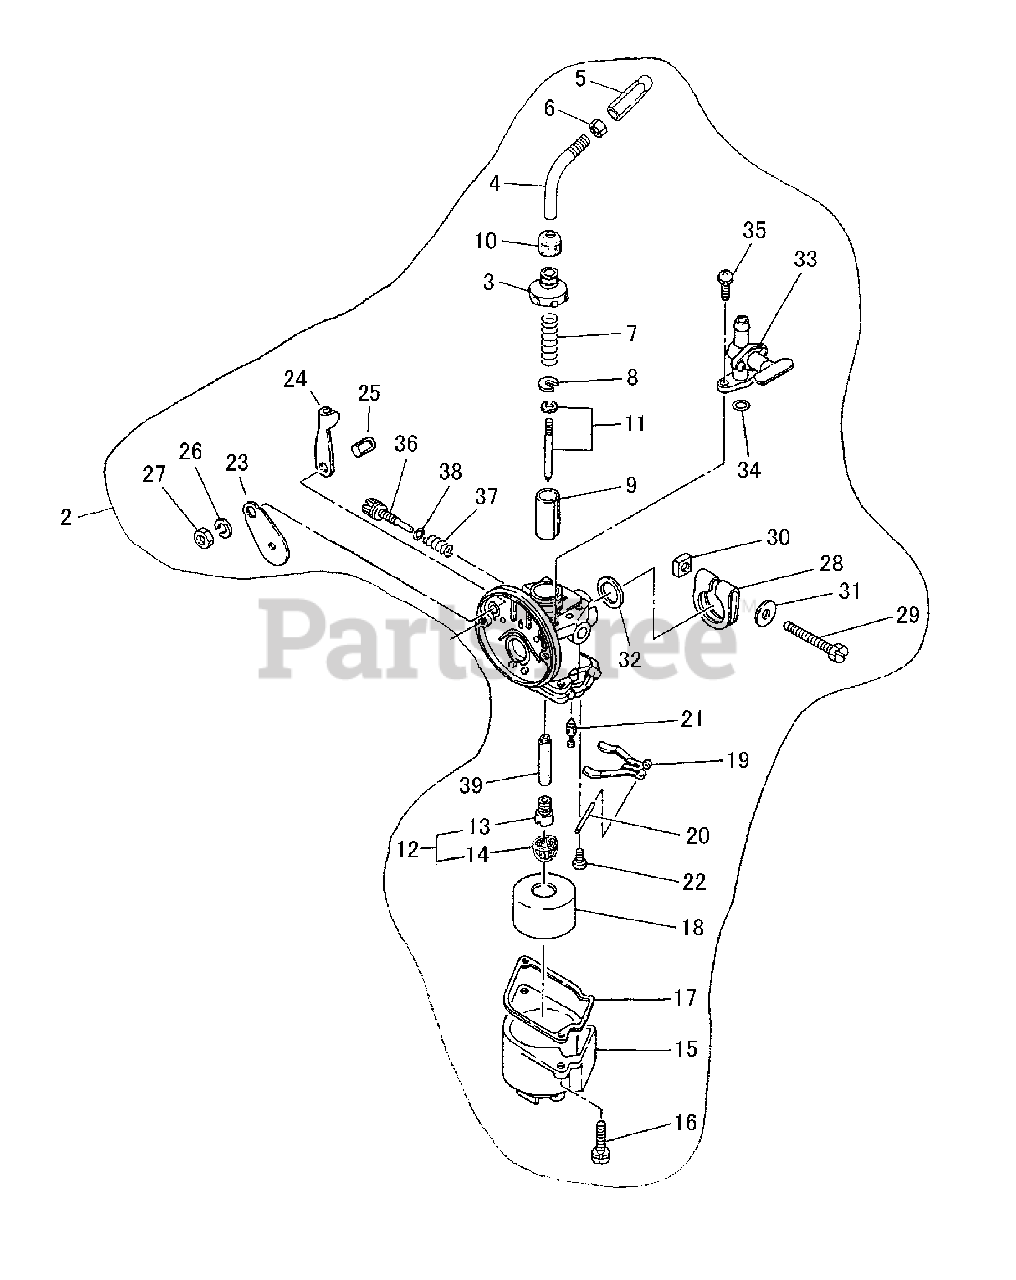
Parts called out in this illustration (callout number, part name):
2	CARBURETOR
3	CAP, CARBURETOR
4	GUIDE, CABLE
5	NUT, CABLE ADJUST
6	LOCKNUT
7	SPRING, THROTTLE
8	RETAINER
9	VALVE, THROTTLE
10	GROMMET
11	NEEDLE, JET
12	MAIN JET ASSY
13	JET, MAIN
14	FILTER, FUEL
15	CHAMBER, FLOAT
17	GASKET, FLOAT CHAMBER
18	FLOAT
19	HINGE, FLOAT
20	PIN, HINGE
21	VALVE, INLET NEEDLE
22	SCREW
23	PLATE, CHOKE
24	LEVER, CHOKE
25	BOLT
26	LOCKWASHER
27	LOCKNUT
28	CLAMP
29	BOLT
31	WASHER
32	SEAL
33	COCK, FUEL
34	O-RING
35	SCREW
36	SCREW, SLOW STOP
37	SPRING
38	O-RING
39	VALVE, INLET NEEDLE
